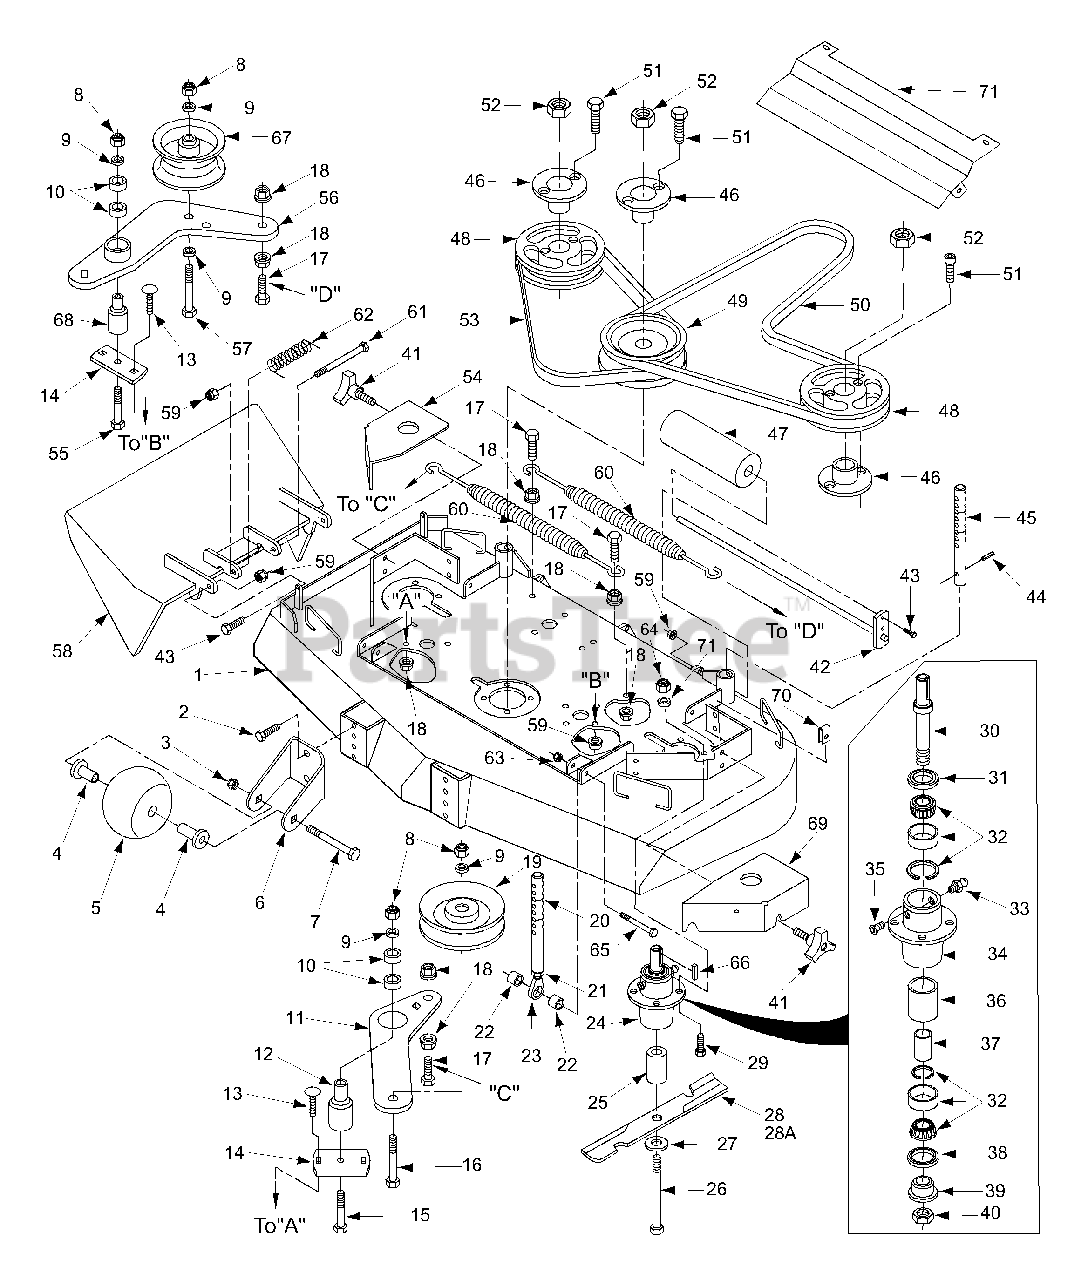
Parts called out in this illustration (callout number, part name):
1	Cutter Deck With Decals 48"
2	Capscrew, 3/8-16 x 1.0" Serrated Flange
3	Lock Nut, 3/8-16 Center Lock
4	Bushing, 376 ID Oilite
5	Wheel, Anti-Scalp
6	Bracket, Anti-Scalp Wheel
7	Bolt, Carriage 3/8-16 x 4.0"
8	Hex Nut, 3/8-16 Elastic Stop
9	Flatwasher, 3/8 (.938 x .391 x .105) Grade 8
10	Ball Bearings
11	Idler Arm RH
12	Pivot, Idle - Short
13	Bolt, Carriage 5/16-18 x 1.0"
14	Base, Idler Pivot
15	Capscrew, Hex Head 3/8-16 x 2.50"
16	Capscrew, Hex Head 3/8-16 x 2.0"
17	Capscrew, Hex Head 3/8-16 x 1.50" Grade 8
18	Nut, 3/8-16 Serrated Flange
19	Pulley, Idler
20	Pin Assembly
21	Nut, 3/8-24 Jam
22	Spacer, Deck Adjustment Pin
23	Rod End, Male 3/8-24
24	Spindle Assembly
25	Spacer, Spindle
26	Bolt,Hex Head 5/8-11 x 9.50"
27	Flatwasher, 5/8 W
28	Cutter Blade 16-1/2" 48"
28	Cutter Blade 18" 52"
28A	Cutter Blade 16-1/2" Hi Lift 48"
28A	Cutter Blade 18" Hi Lift 52"
29	Bolt, Hex Head 5/16-18 x 1.50"
30	Spindle Shaft
31	Seal, Cutter Spindle - Top
32	Tapered Bearings (Two)
33	Grease Fitting
34	Spindle Housing
35	Relief Fitting, Cutter Spindle
36	Spacer Outside
37	Spacer, Inside
38	Seal, Cutter Spindle - Bottom
39	Spindle Bushing
40	Nut, Spindle
41	Wing Nut, 3/8-16
42	Roller Shaft
43	Bolt, Hex Head 5/16-18 x 1.0" Front
43	Bolt, Hex Head 5/16-18 x 1.50" Rear
44	Pin, Slotted Spring 3/16 x 1.50"
45	Pin, Deck Adjustment Rear
46	Tapered Hub
47	Guide, Roller
48	Pulley
49	Pulley, 5.75 Double Groove
50	Belt, Deck Drive
51	Capscrew, Socket Head 1/4-20 x 1.375"
52	Hex Nut, 5/8-11
53	Belt, RH Blade Drive 48"
53	Belt, RH Blade Drive 52"
54	Belt Cover, RH
55	Capscrew, Hex Head 3/8-16 x 3.25"
56	Idler Arm Weldment
57	Capscrew, Hex Head 3/8-16 x 3.75"
58	Discharge Chute, Nylon
59	Nut, 5/16-18 Serrated Flange
60	Spring, Deck Idler
61	Bolt, Hex Head 5/16-18 x 4.75"
62	Spring, Chute Return
63	Nut, 3/8-16 Elastic Stop
64	Nut, 5/16-18 Elastic Stop
65	Bolt, Hex Head 3/8-16 x 2.50"
66	Key, 1/4 x 1/4 x 2.0"
67	Pulley, Idler
68	Pivot, Idler - Long
69	Belt Cover LH
70	U-Nut, 3/8-16
71	Lockwasher, 5/16 (.317 x .586 x .078)
